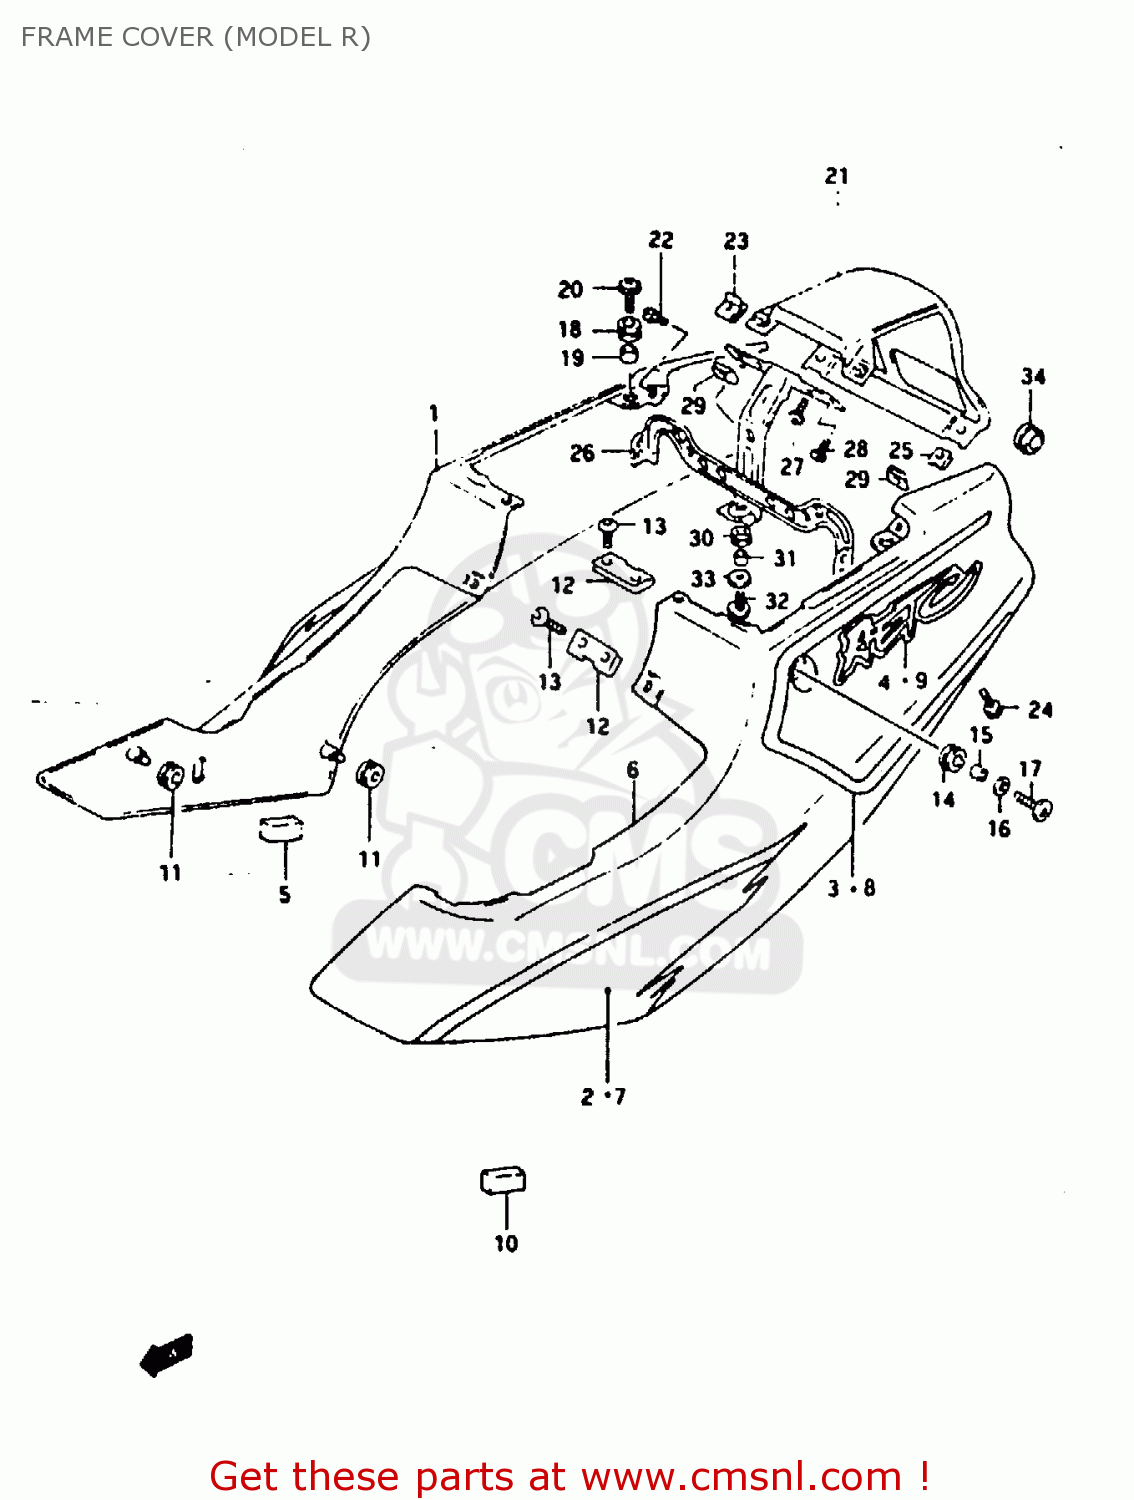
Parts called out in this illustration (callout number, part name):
1	COVER, FRAME RH (WHITE)
2	TAPE, FRAME COVER RH
3	TAPE, ZEKKEN RH
4	EMBLEM, LH
5	RUBBER,FRAME COVER
6	COVER, FRAME LH (WHITE)
7	TAPE, FRAME COVER LH
8	TAPE, STICKER LH
9	EMBLEM, LH
10	RUBBER,FRAME COVER
11	CUSHION
12	NUT,FRAME COVER CTR
13	SCREW
14	CUSHION
15	SPACER (6.3X9.1X6.7)
16	WASHER(6.5X22X1.6)
17	SCREW
18	CUSHION
19	SPACER (6.3X9.1X6.7)
20	SCREW(6X20)
21	COVER, FRAME CENTER (GRAY)
22	SCREW
23	NUT
24	SCREW
25	NUT
26	BRACKET,TAIL LAMP RR
27	SCREW
28	SCREW
29	NUT
30	CUSHION
31	SPACER (6.1X8X9.5)
32	BOLT(6X20)
33	WASHER
34	GROMMET
42	WASHER
43	GROMMET
